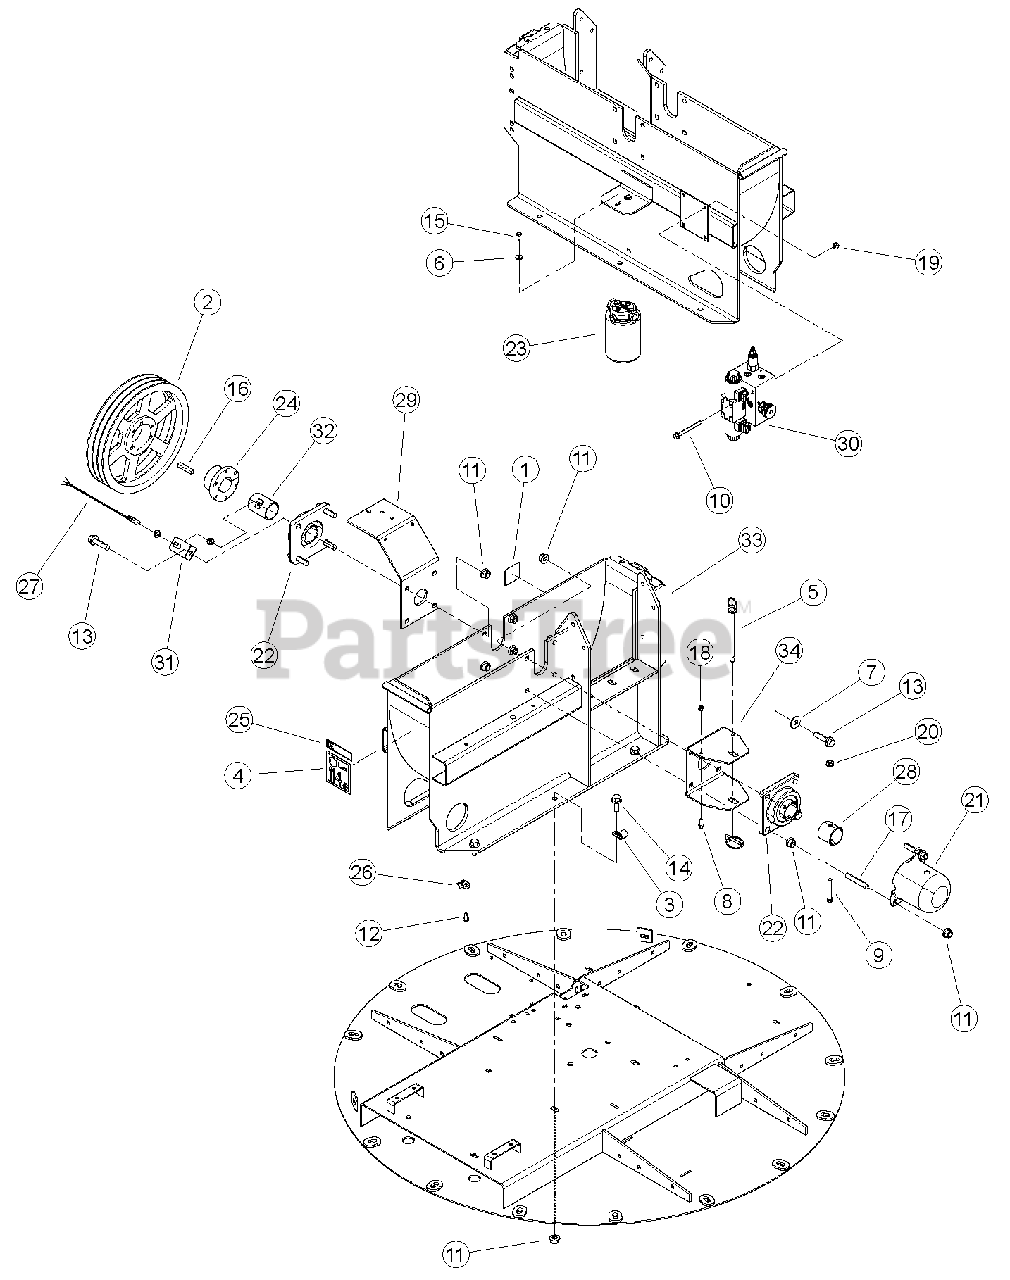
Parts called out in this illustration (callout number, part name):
1	DECAL, SHIELD DANGER ISO
2	SHEAVE, 3BQ12.4, SK
3	CLAMP, 9/16 COATED
4	DECAL, 114 DB (CE COMPLIANT ONLY)
5	PIN, HITCH 1/2 X 6-1/2 W/ LYNCH
6	WASHER, 1/4" FLAT ZP
7	WASHER, 1/2" FLAT ZP
8	BOLT, 1/4-20X3/4 HWH GR5 CZP
9	BOLT, 3/8 X 2-1/2 GR5 HHCS ZP
10	BOLT, 5/16 X 3-1/2 SERRATED FLANGE NC
11	NUT, 1/2-13 NYLOCK FLANGE
12	SCREW, 11/32 X 7/8 HWH AB THREAD ZP
13	BOLT, 1/2-13 X 2 HWH GR5 CZP
14	BOLT, 1/2 -13 X 1-1/4 FLANGE NC
15	BOLT 1/4 X 5/8" HHCS GR5 ZP
16	KEY, 3/8" SQ X 2" LG PLAIN
17	STUD, 1/2"-13 X 3" LG B7 ZP
18	NUT, 1/4-20 NYLOCK-FLANGE
19	NUT, 5/16-18 NYLOCK-FLANGE
20	NUT, 3/8-16 NYLOCK FLANGE
21	CAP, LARGE SHAFT
22	BEARING, 1-3/4 4 BOLT FLANGE
23	ASSEMBLY, HYDRAULIC FILTER
24	BUSHING, SK 1-3/4"
25	DECAL, 76835 INFORMATION (CE COMPLIANT ONLY)
26	CLAMP, CABLE MOUNT
27	SENSOR, M12 PNP PROXIMITY (REPLACEMENT PART)
28	COLLAR, CHIPPER LOCK
29	WELDMENT, REAR GUARD SUPPORT
30	ASSEMBLY, HYDRAULIC FEED FLOW VALVE W/ PS
31	BRACKET, PROXIMITY SENSOR
32	WELDMENT, SPACER 2.0 X 2.30
33	WELDMENT, CHIPPER BOTTOM
34	BRACKET, ROTOR LOCK
